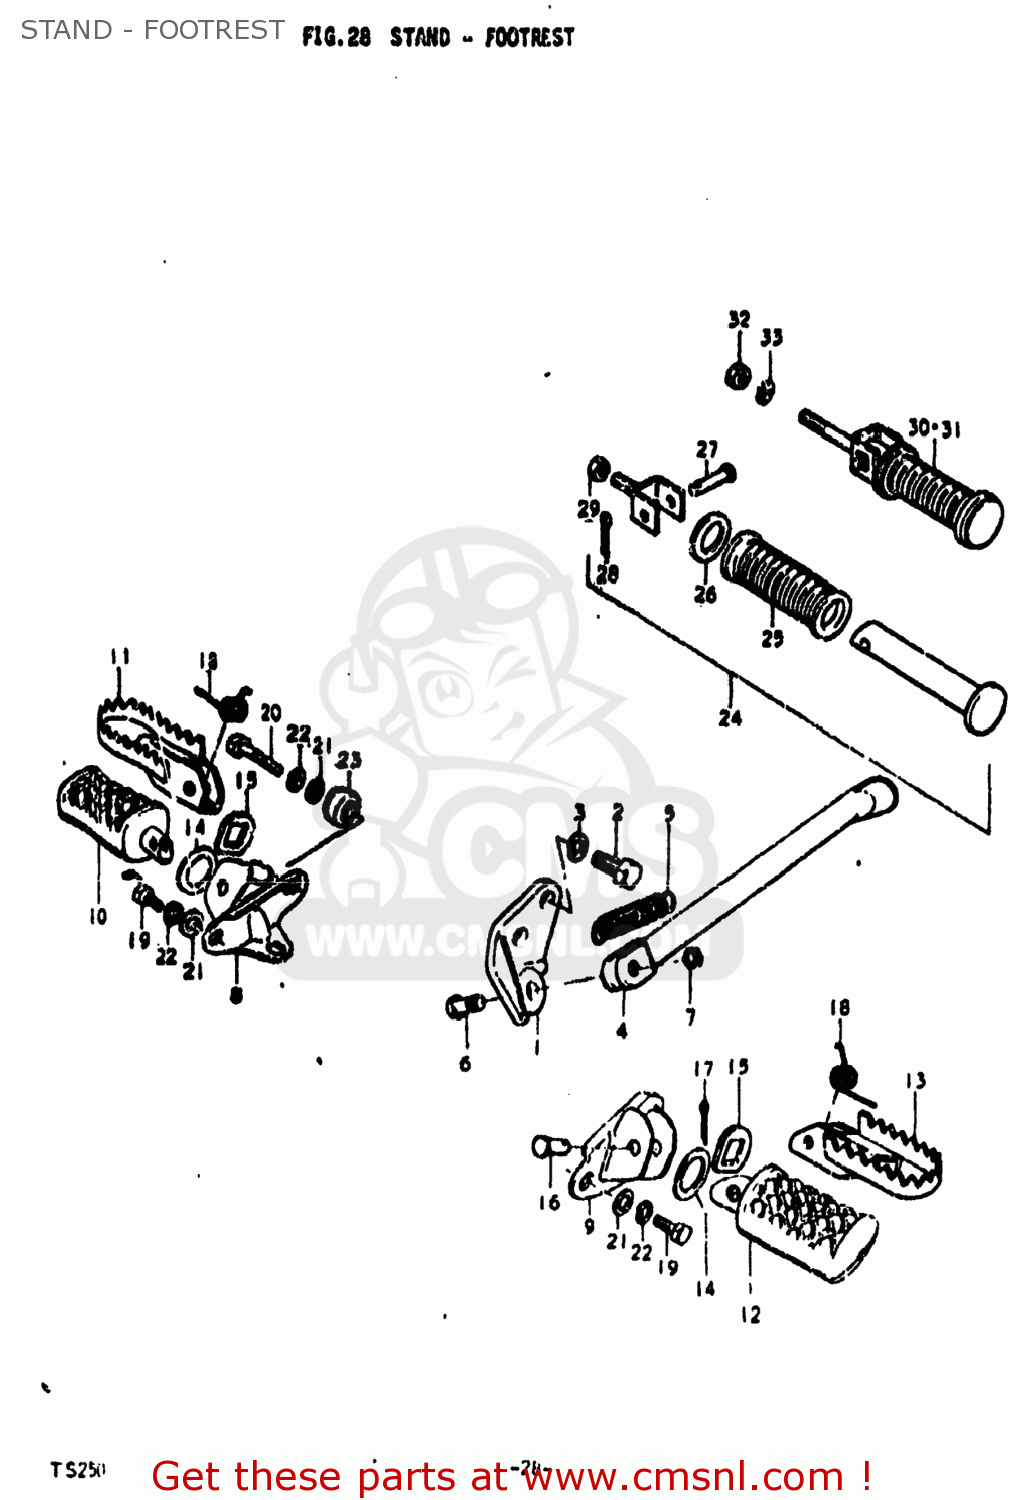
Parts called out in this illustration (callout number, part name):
1	BRACKET,SIDE STAND
2	BOLT 10X25
3	LOCK WASHER
4	STAND,SIDE
5	SPRING
6	BOLT(10X30)
7	NUT
8	BAR,FRONT FOOTREST
9	HOLDER,FRONT FOOTREST
10	RUBBER,FOOTREST,RIGHT
11	RUBBER,FOOTREST,RIGHT
12	RUBBER,FOOTREST,LEFT
13	RUBBER,FOOTREST,LEFT
14	WASHER
15	WASHER
16	PIN
17	PIN 20X20
18	SPRING
19	BOLT
20	BOLT 8X40
21	WASHER
22	WASHER,LOCK,8.
24	FOOTREST ASSEMBLY,REAR
25	RUBBER,PILLION FOOTREST
26	WASHER (19.5X32X2)
27	PIN
28	PIN 20X20
29	NUT
30	FOOTREST ASSY,PILLION
31	FOOTREST ASSEMBLY,REAR
32	NUT
33	WASHER,LOCK 12
